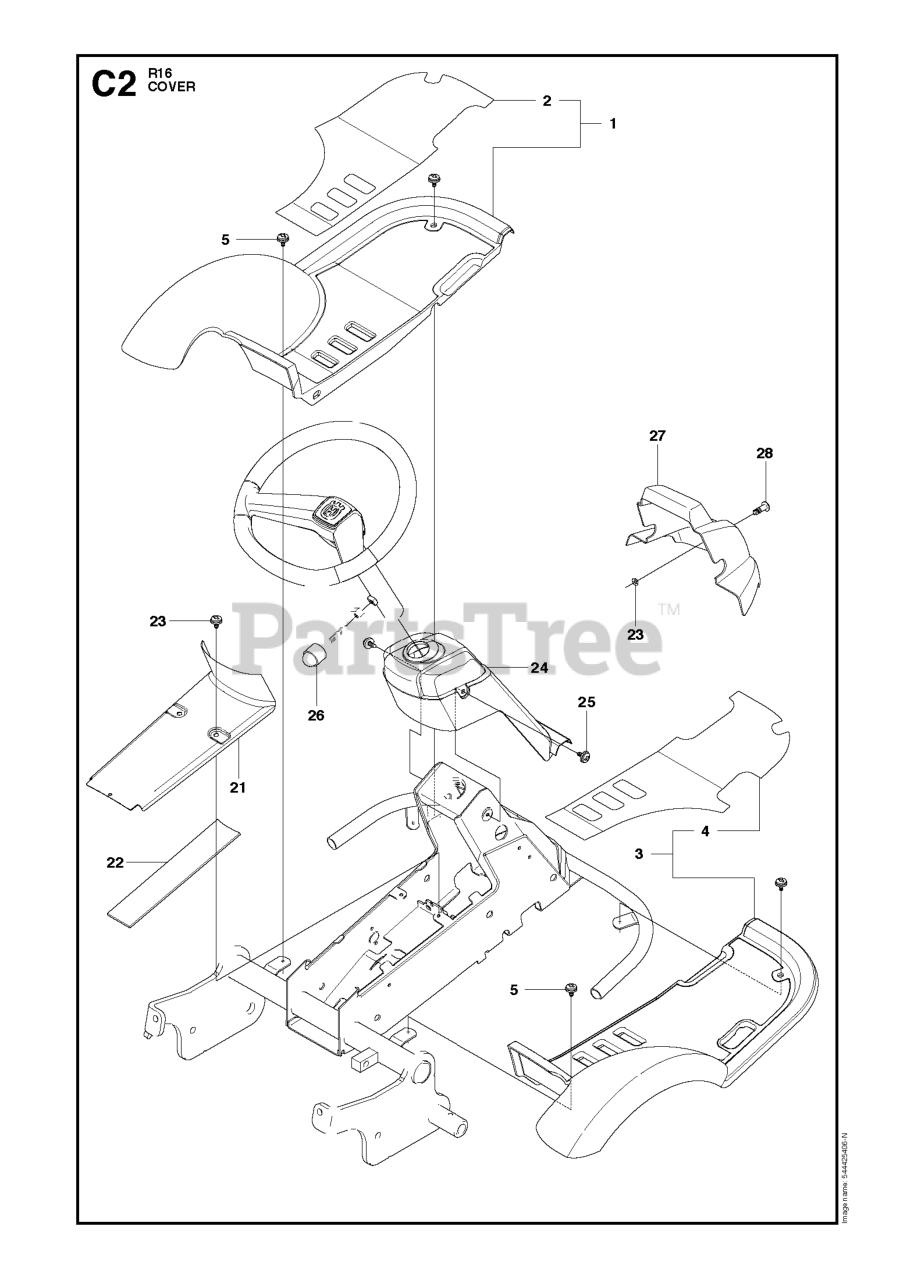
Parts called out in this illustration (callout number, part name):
1	FOOT PLATE
3	FOOT PLATE
26	PROTECTIVE COVER
